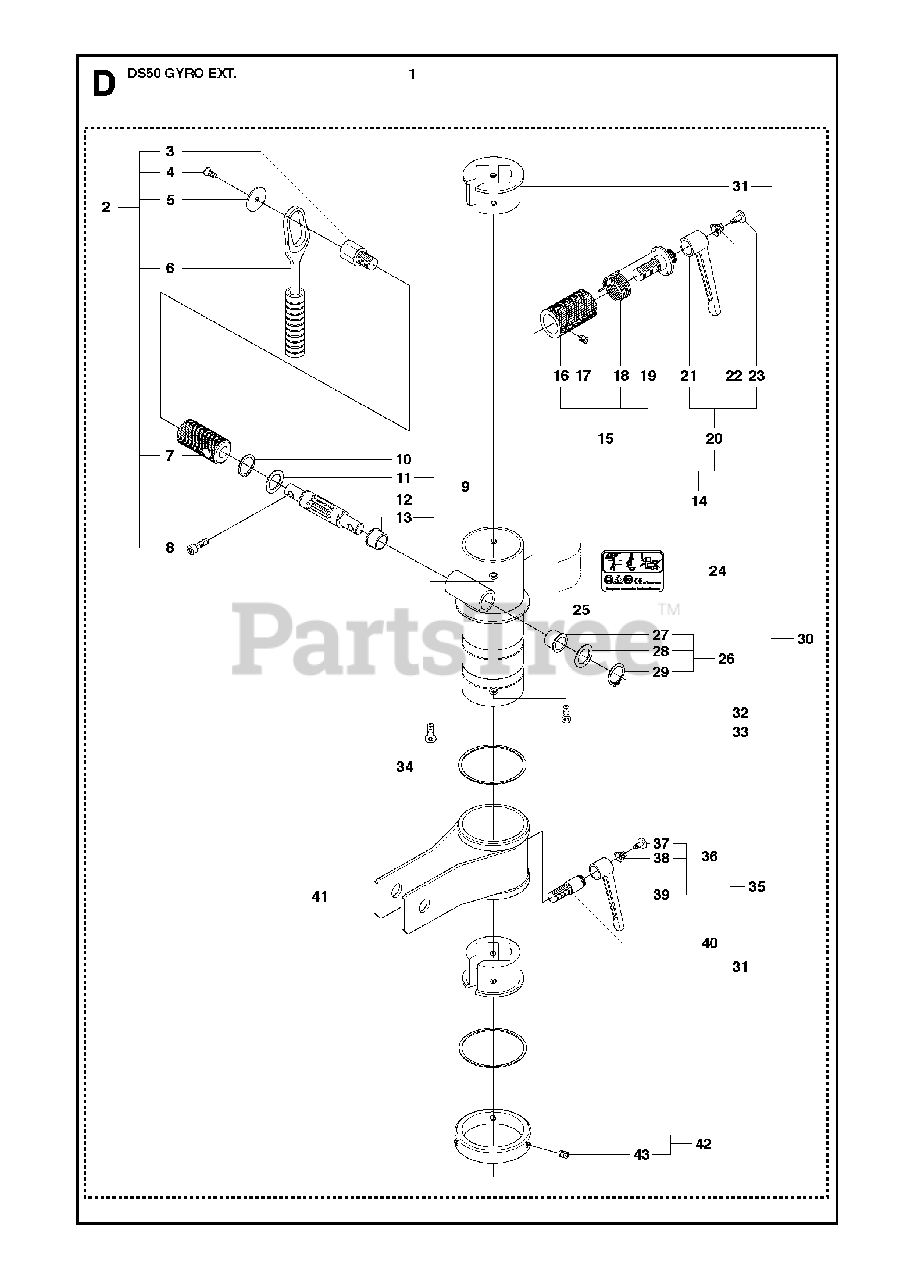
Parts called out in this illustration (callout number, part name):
1	BRACKETIncl. 2, 9, 14, 24-26, 30, 35-36, 42-43
15	SPRING RETAINERIncl. 16-19
36	HANDLEIncl. 37-39
